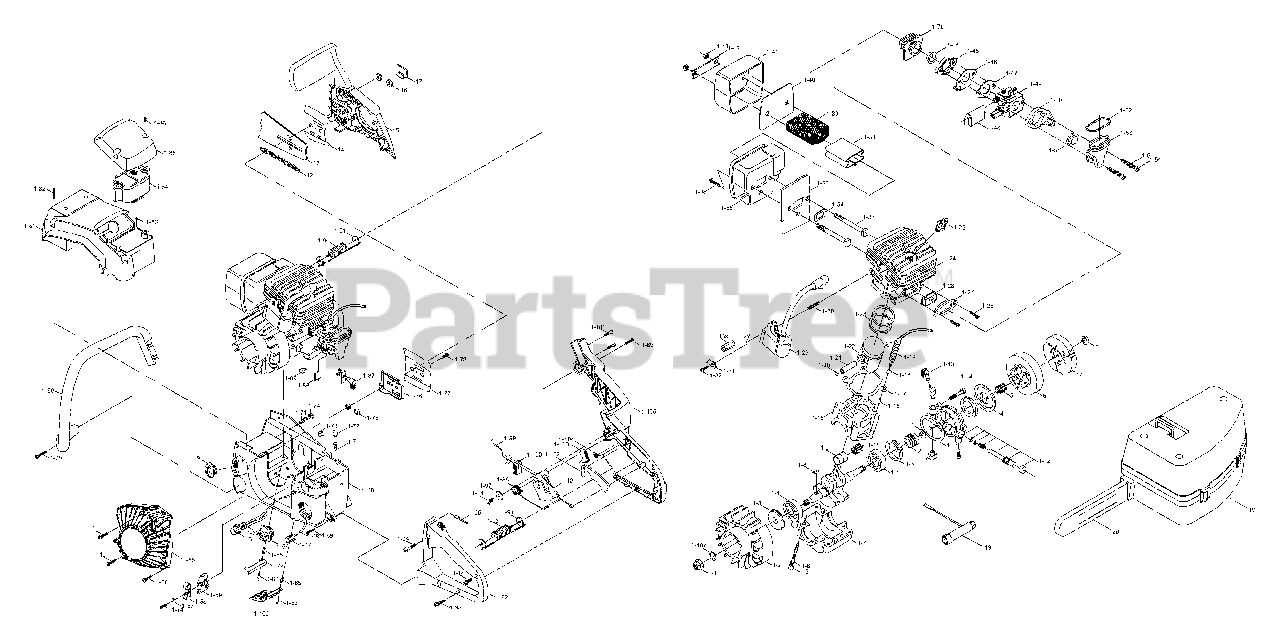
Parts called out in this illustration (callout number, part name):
1	POWERHEAD ASS'Y
1-7	CRANKCASE LOWER
1-9	C'SHAFT/C'ROD ASS'Y
1-12	PUMP ASS'Y
1-15	FITTING, PULSE LINE
1-16	CRANKCASE UPPER
1-18	CLAMP, WIRE HOSE
1-19	CONDUIT, FLEX
1-25	SPARK PLUG
1-26	SCREW
1-29	IGNITION ASS'Y
1-31	CONTACT. CROUNT
1-36	MUFFLER BODY ASS'Y
1-41	COVER, MUFFLER
1-42	LOCKPLATE
1-55	STARTER ASS'Y
1-60	FUEL/OIL TANK ASS'Y
1-61	PRIMER REMOTE
1-71	VALVE DUCKBILL
1-77	PLATE, FLANGE
1-80	HANDLE ASS'Y
1-81	COVER ASS'Y
1-84	AIR CLEANER ASS'Y
1-87	CHOKE ASS'Y
1-88	ROD, CHOKE
1-90	ISOLATOR ASS'Y
1-91	CABLE ASS'Y
1-92	COVER ASS'Y, HANDLE
1-96	ISOLATOR ASS'Y
1-102	RELEASE, TRIGGER
1-103	LATCH, HIGH IDLE
2	GEAR, WORM
6	DRUM SPRKT ASS'Y
7	CLUTCH ASS'Y
12	CHAIN 78EB
13	BAR (TROY-BILT LOGO)
15	CHAIN BRAKE ASS'Y
19	CARRY CASE
